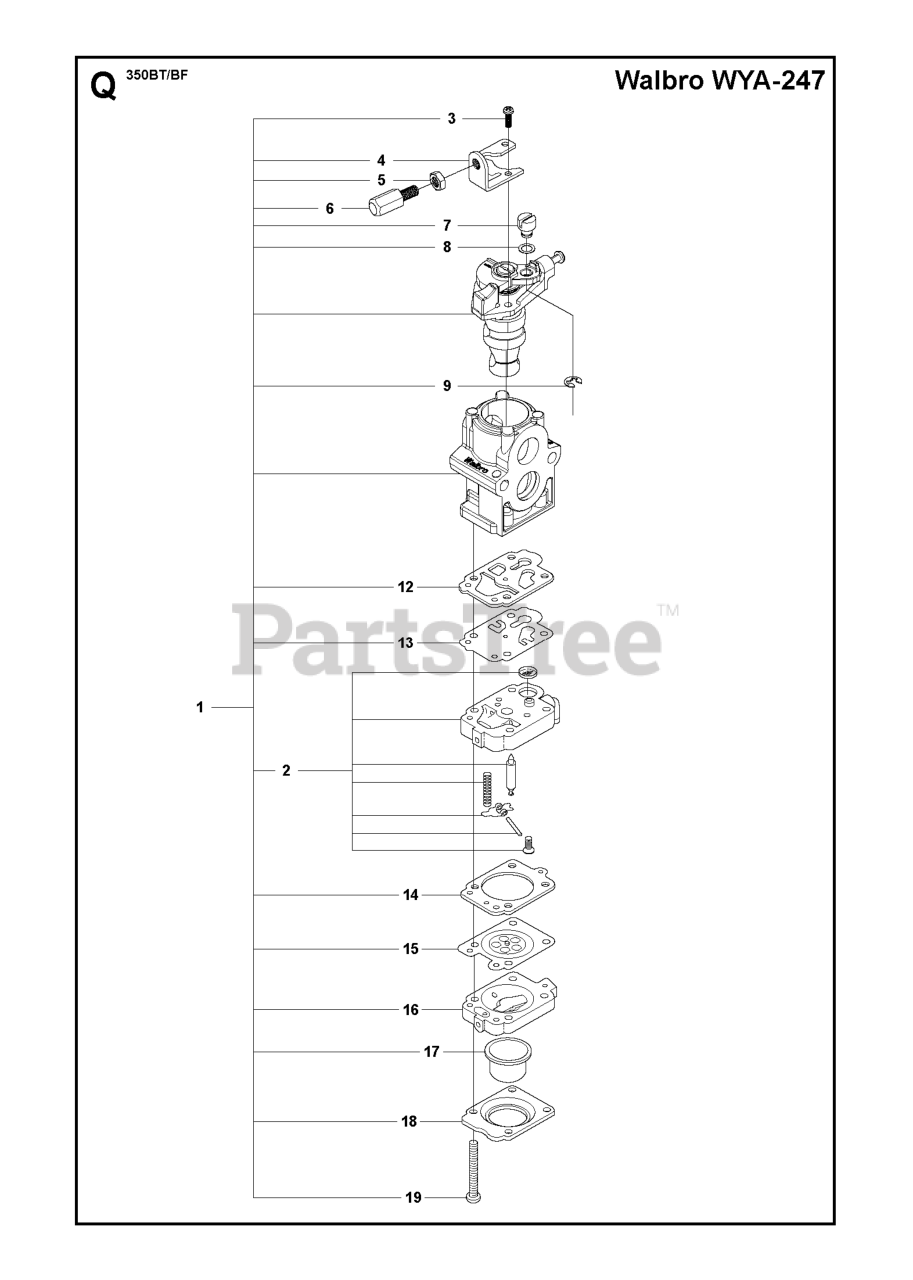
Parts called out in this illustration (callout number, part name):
1	CARBURETTOR
2	BODY-A-PUMP
5	NUT
6	ADJUSTER
